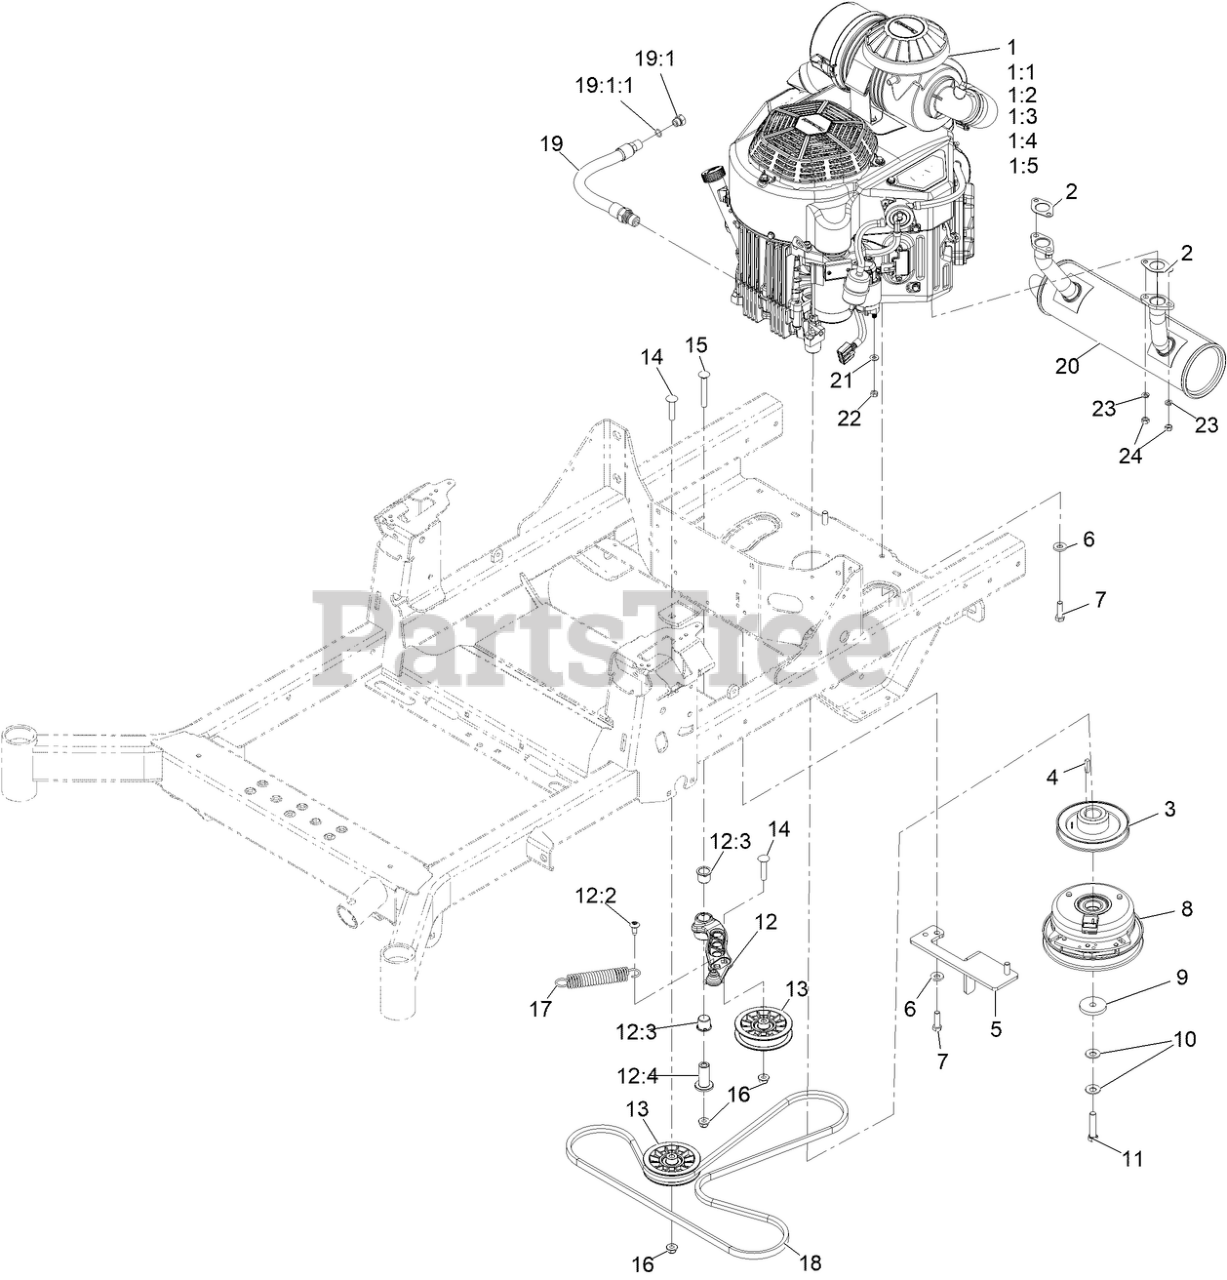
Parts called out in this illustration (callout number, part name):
1:5	SPARK PLUG
2	GASKET-EXHAUST
3	SHEAVE, ENGINE
5	Anchor-Clutch
6	WASHER-BELLEVILLE
7	SCREW-HH
9	WASHER-CLUTCH
10	WASHER-SPRING
11	SCREW-HH W/LOCTITE
12	ASM, PUMP IDLER
12:2	SCREW, TAPTITE
12:3	BUSHING, IGUS
12:4	Spacer, Idler Pivot
13	PULLEY-FLAT IDLER
14	SCREW-CARR
15	SCREW-CARR
16	NUT-HF, NI
17	SPRING-EXTENSION
18	BELT-V
19	ENGINE OIL DRAIN HOSE ASM
19:1	PLUG-HH
19:1:1	O-RING
20	MUFFLER, KAWASAKI
21	WASHER-FLAT
22	NUT-HEX
23	WASHER-LOCK
